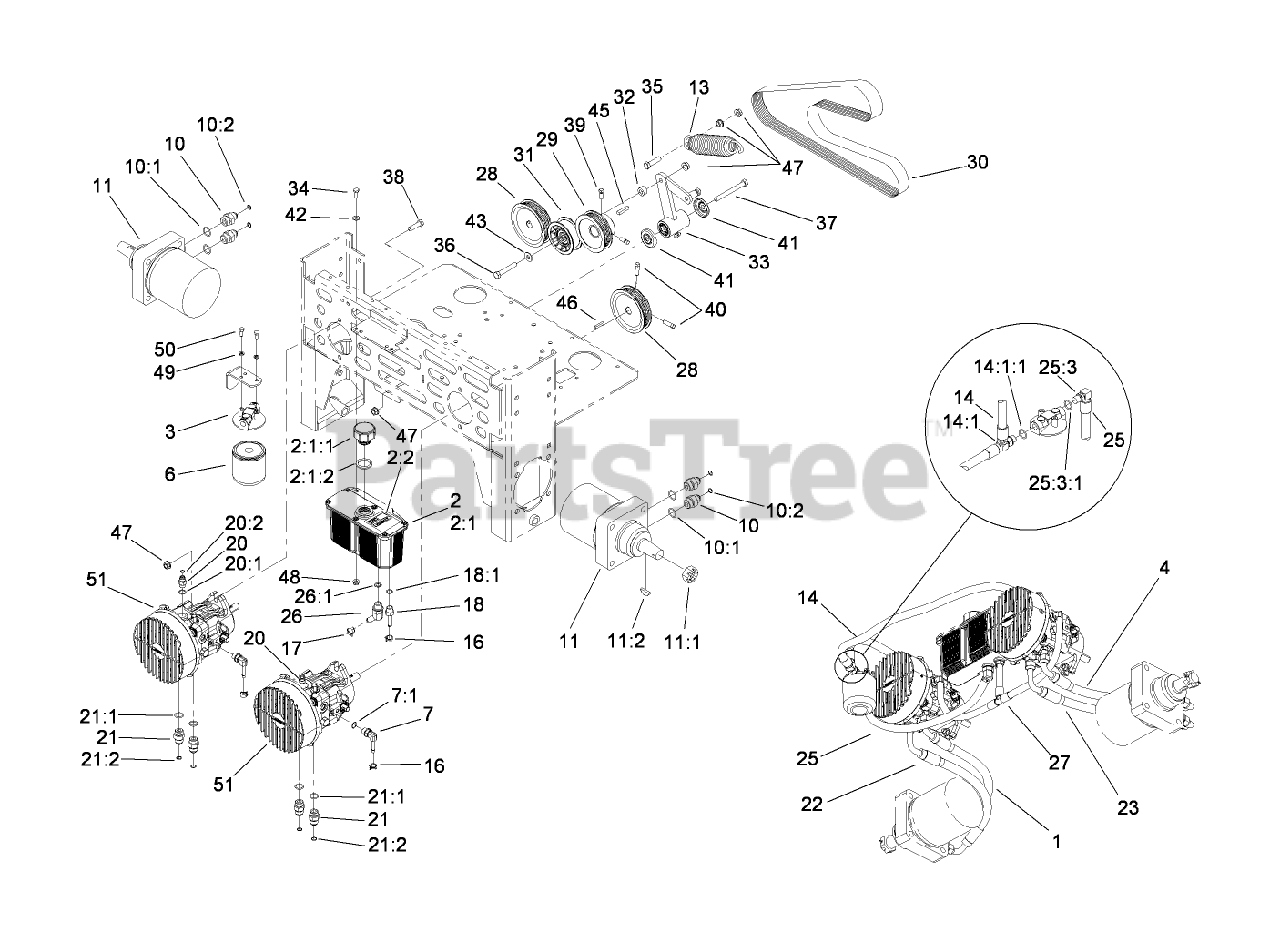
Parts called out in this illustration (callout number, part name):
1	HYD HOSE ASM
2	HYD Reservoir ASM
2:1	Reservoir-HYD
2:1:1	CAP-RESERVOIR, HYD
2:1:2	GASKET-CAP
2:2	DECAL-TANK, HYD
3	HEAD-FILTER
4	HYD HOSE ASM
6	FILTER-OIL, HYD
6	FILTER-OIL, HYD (WINTER)
7	ELBOW-90 DEG
7:1	O-RING
10	Fitting-Straight
10:1	O-RING
10:2	O-Ring
11	MOTOR-WHEEL
11:1	NUT-HH
11:2	KEY-WOODRUFF
13	Spring-Extension
14	HYD HOSE ASM
14:1	ADAPTER-RUN, TEE
14:1:1	O-RING
16	Clamp-Hose
17	Clamp-Hose
18	Adapter-Straight
18:1	O-RING
20	FITTING-STRAIGHT
20:1	O-Ring
20:2	O-RING
21	FITTING-STRAIGHT
21:1	O-RING
21:2	O-Ring
22	HYD HOSE ASM
23	HYD HOSE ASM
25	HYD HOSE ASM
25:3	FITTING-BARB
25:3:1	O-RING
26	FITTING-BARBED, 45 DEG
26:1	O-RING
27	HYD Hose ASM
28	SHEAVE
29	SHEAVE
31	PULLEY-FLAT IDLER
32	SPACER
33	PUMP IDLER ASM
34	SCREW-HH
35	SCREW-HH
36	SCREW-HH
37	SCREW-HH
38	SCREW-HH
39	SCREW-SET
40	SCREW-SET
41	GUARD-TOP
42	WASHER-FLAT
43	WASHER-FLAT
45	KEY-SQUARE
46	KEY-SQUARE
47	NUT-HHF, WHIZ
48	NUT-HF
49	WASHER-LOCK
50	SCREW-HH
51	PUMP-HYD, 12CC W/FAN
